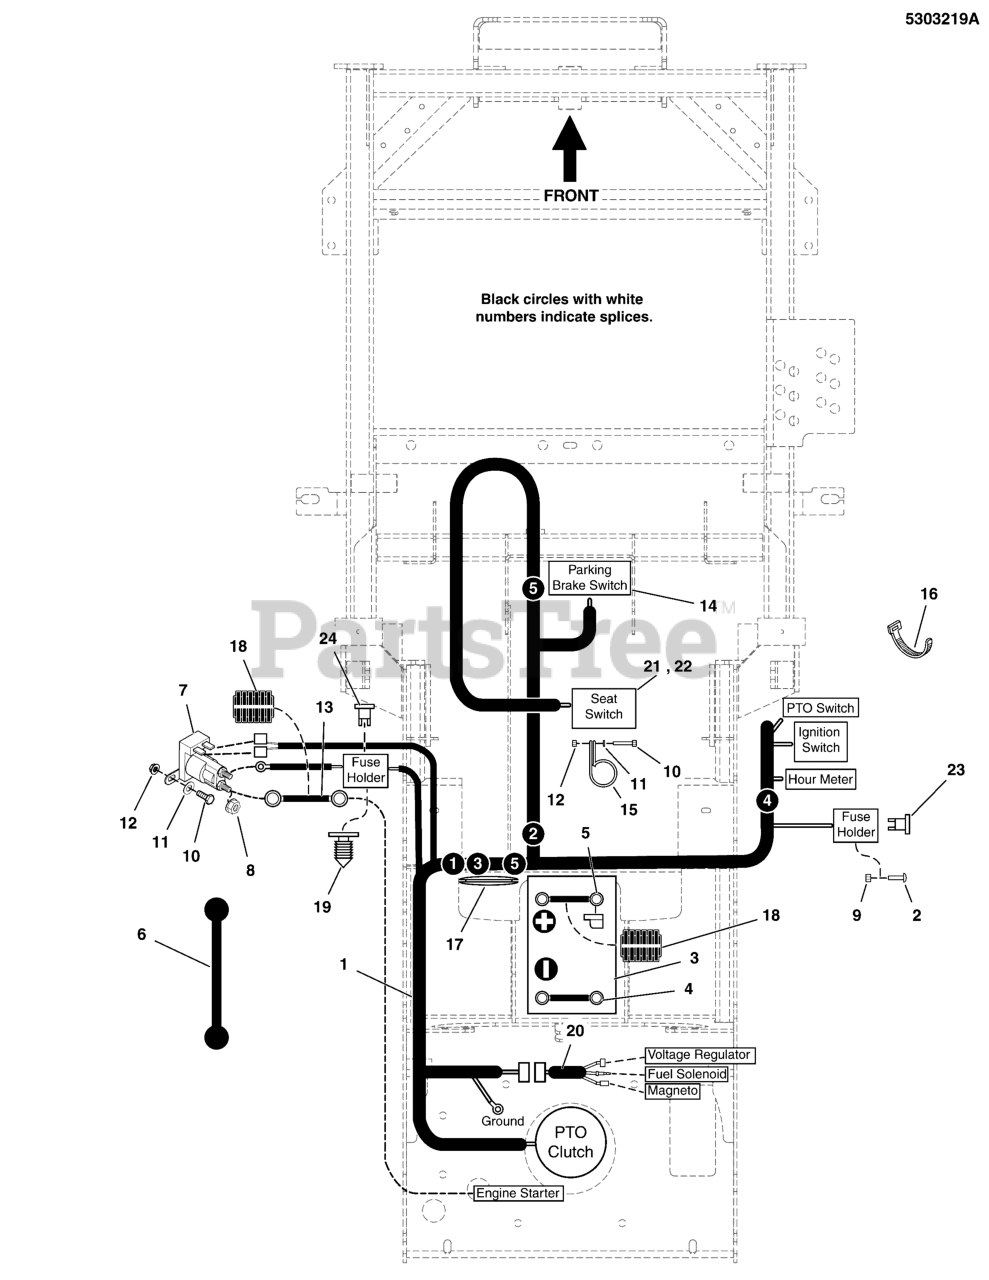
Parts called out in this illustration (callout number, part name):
1	WIRE HARNESS, MAIN, SM, ZTR
1	HARNESS, Wiring, Small ZTR
3	BATTERY, WET ( BCIU1, 350 CCA)
4	BATTERY CABLE, NEG, 14, 5/16-13/32
5	BATTERY CABLE, POS, 22, 1/4-5/16
6	STRAP, BATTERY, 14 LONG, Rubber
7	SOLENOID, STD-BRACKET, 2-SPADE
8	NUT,1/4-20,KEPS,CONICAL WSHR,ZC/CL
9	NUT, Hex, 5/16-24
10	BOLT, 1/4"-20 X 3/4" GD5 YZ
11	WASHER, 1/4 SAE
12	NUT, 1/4-20 Hex Nylock Flange
13	BATTERY CABLE, POS, 22, 1/4-5/16
14	SWITCH, DP NO/NC SNAP-IN
15	CLAMP, VINYL INSULATED, 1.00
16	TIE, SELF-LOCKING, 12"
17	GROMMET, 1-1/2" ID FOR 1/4" METAL
18	WIRE LOOM, 3/8 ID X 18 IN
19	FIR TREE MOUNT, PACKARD
20	WIRE HARNESS, JUMPER, KAWI
21	SWITCH, NC, W/ BOLT-IN BASE
22	SWITCH, NC, W/ TWIST-IN BASE
23	FUSE, ATO-15 (15 AMP)(SV)
24	FUSE, ATO-20 (20 AMP)(SV)
